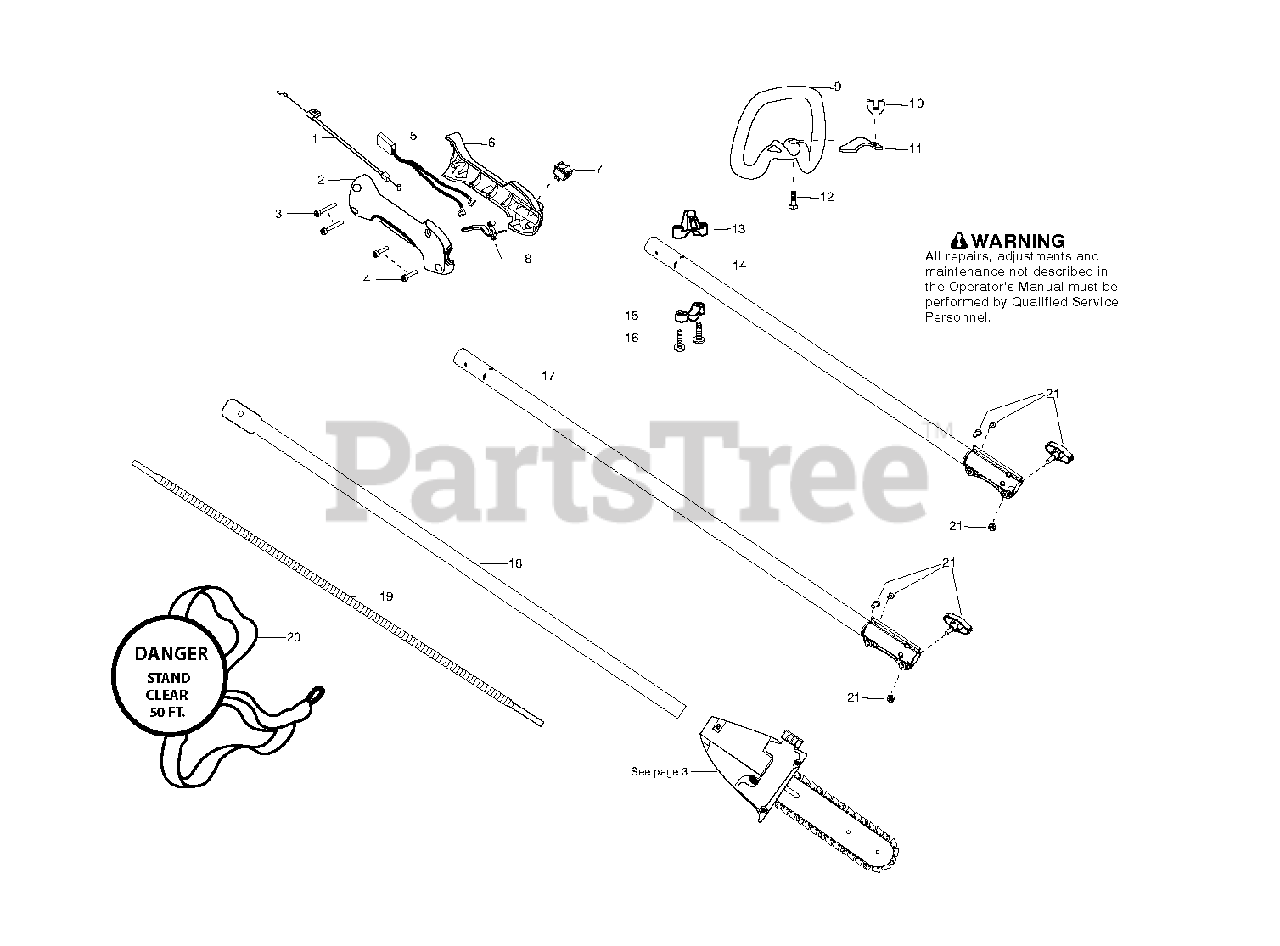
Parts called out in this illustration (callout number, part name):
1	ASSY THROTTLE CABLE
2	HOUSING THROTTLE FAN
3	SCREW #10 PLASTITE 1.362
5	WIRE ASSY
6	HSG THROTTLE LH
7	Switch Kit
8	TRIGGER RED
9	ASSY HANDLE GAS ASSIST 1
10	WINGNUT, TYPE 2
11	CLAMP ASSIST HANDLE
12	BOLT, TYPE 2
13	CLAMP HARNESS UPPER
14	UPPER SHAFT KIT
15	CLAMP LOWER HARNESS
17	TUBE
18	ASSY D'SHAFT SVC 24" BLACK
19	FLEX-LOWER
20	ASSY,SHOULDER STRAP
21	ASSY COUPLER BLACK
